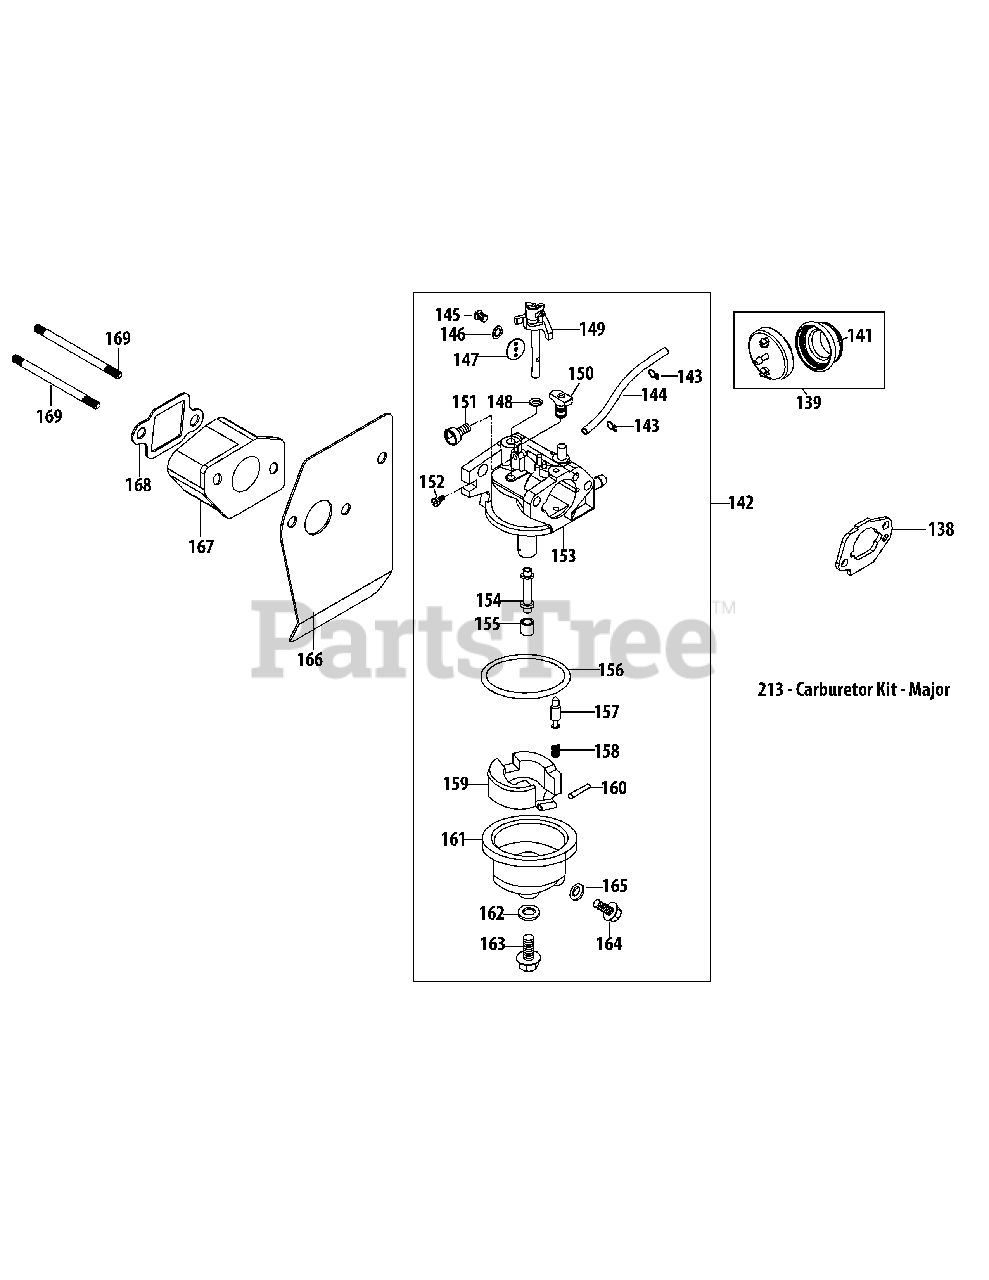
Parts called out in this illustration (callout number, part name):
138	Carburetor Gasket Plate
139	Primer Assembly
141	Primer Bulb
142	Carburetor Assembly
143	Primer Hose Clamp
144	Primer Hose
145	Screw M3X6 Throttle Plate
146	Throttle Plate Lock Washer
147	Throttle Plate
148	Throttle Shaft Fiber O-Ring
149	Throttle Shaft
150	Idle Jet Assembly
151	Idle Speed Adjusting Screw
152	Idle Mixture Screw
153	Carburetor Body
154	Emulsion Tube
155	Main Jet
156	Fuel Bowl O-Ring
157	Needle Valve
158	Needle Valve Spring
159	Float
160	Float Pin
161	Fuel Bowl
162	Fuel Bowl Gasket
163	Fuel Bowl Mounting Bolt
164	Fuel Drain Plug
165	Fuel Drain Plug Gasket
166	Carburetor Gasket
167	Carburetor Insulator
168	Carburetor Insulator Gasket
169	Carb Stud M6X113
213	Carburetor Kit - Major
